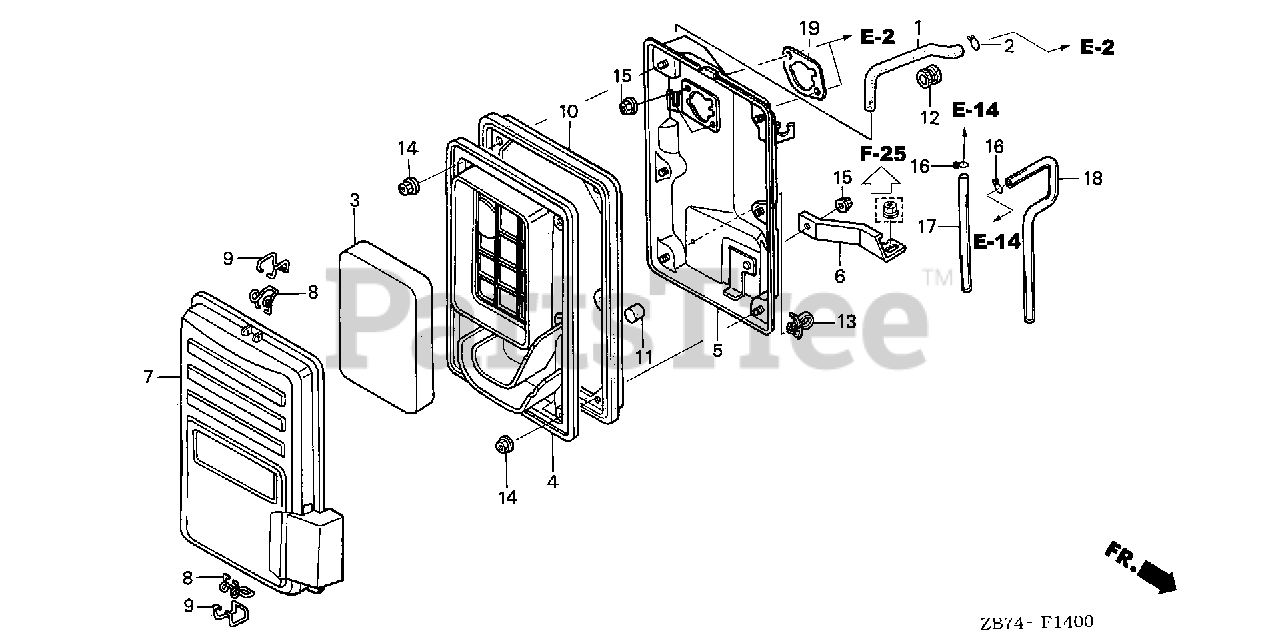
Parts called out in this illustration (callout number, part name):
1	TUBE, BREATHER
2	CLIP, BREATHER TUBE
3	ELEMENT, AIR CLEANER
4	SEPARATOR, AIR CLEANER
5	HOUSING, AIR CLEANER
6	STAY, AIR CLEANER
7	COVER, AIR CLEANER
8	CLIP A, AIR CLEANER WIRE
9	CLIP B, AIR CLEANER WIRE
10	SEAL, AIR CLEANER
11	FILTER, DRAIN TUBE
12	GROMMET, FENDER
13	CLIP, WIRE HARNESS
14	NUT, FLANGE (5MM)
15	NUT, FLANGE (6MM)
16	CLIP, TUBE (4.5)
17	BULK HOSE, VINYL (4.5X8X1000) (4.5X8X750)
18	BULK HOSE, VINYL (4.5X8X1000) (4.5X8X750)
19	GASKET, AIR CLEANER
